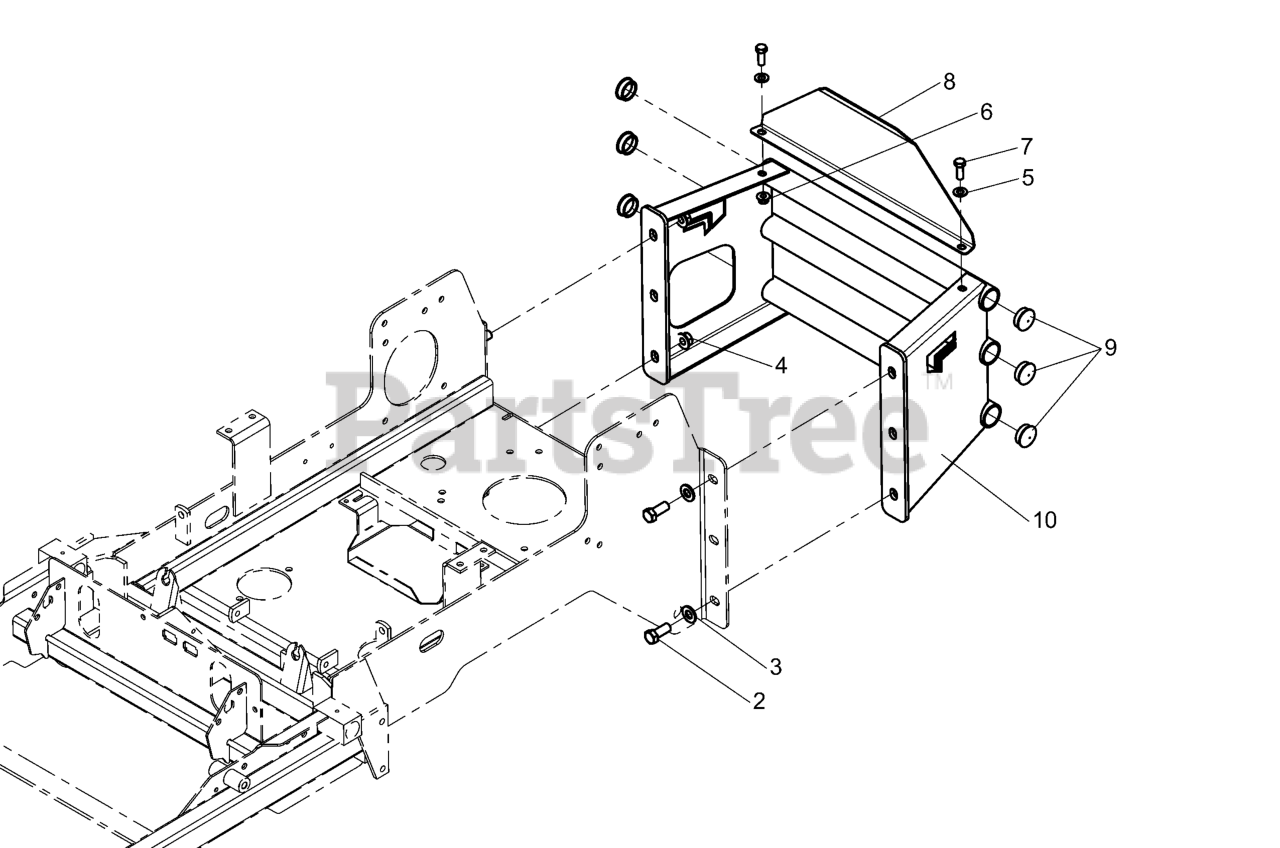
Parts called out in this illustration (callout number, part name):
2	BOLT, 1/2-20 X 1-1/4" GD5 CZ
3	WASHER, 1/2 SAE
4	NUT, 1/2-20 Hex Nylock Flange
5	WASHER, 3/8 SAE
6	NUT, 3/8-16 Hex Nylock Flange
7	BOLT, 3/8-16 X 1" GD5 CZ
8	PLATE, CARB PROTECTOR
9	PLUG, PANEL, 1.25 BLACK
10	WELD, BUMPER
